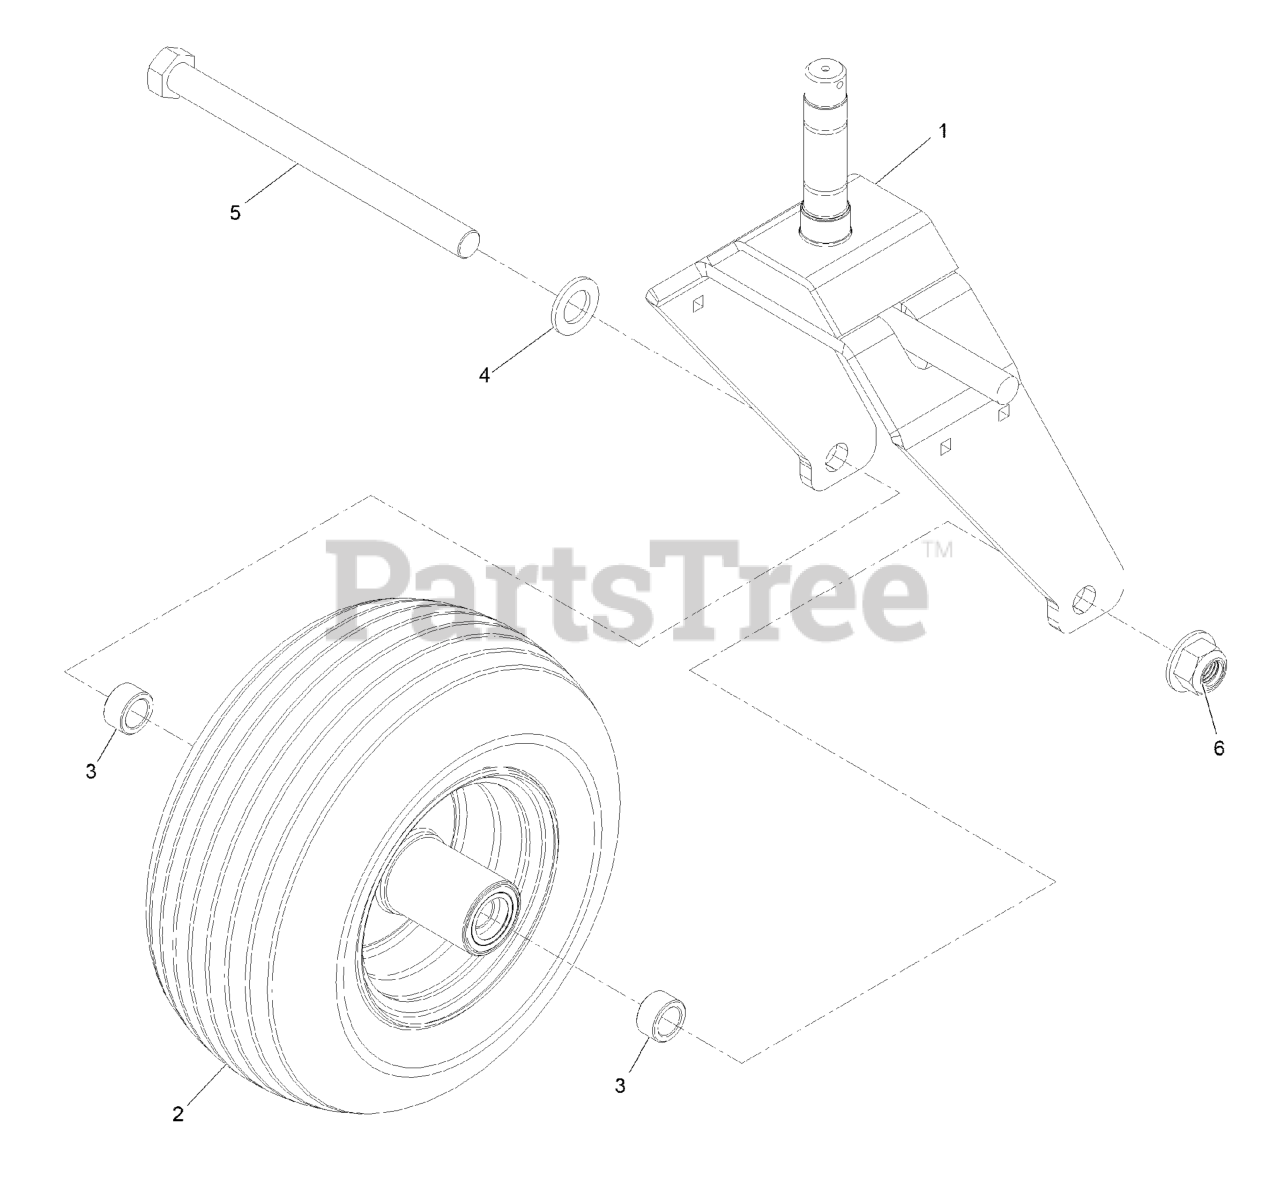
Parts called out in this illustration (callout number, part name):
1	Fork-Caster, RH [red]
2	WHEEL AND TIRE
3	SPACER-AXLE
5	SCREW-HH
